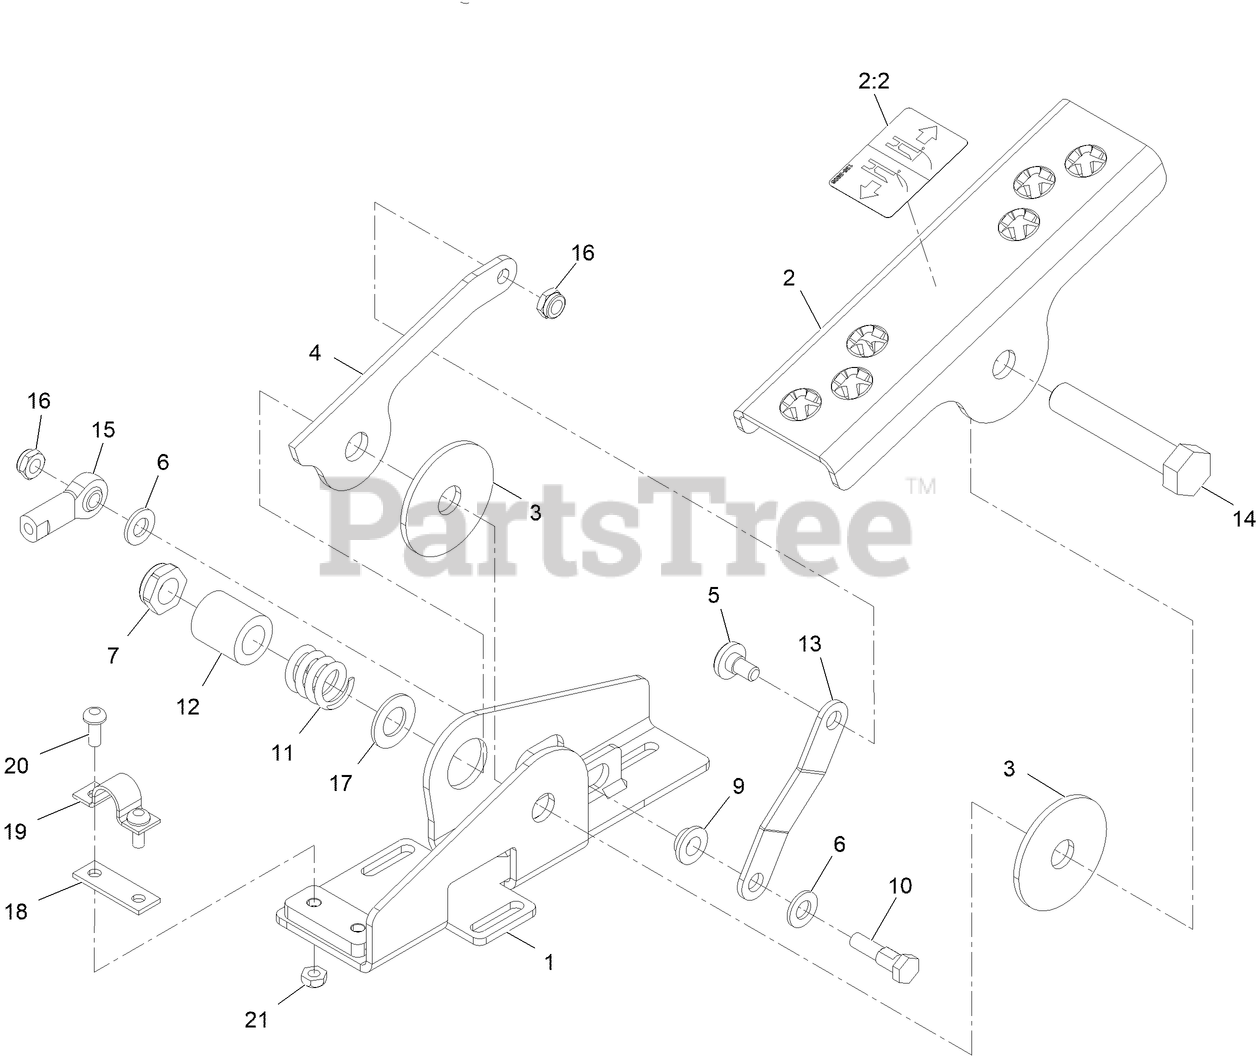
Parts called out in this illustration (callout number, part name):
1	WELD, PEDAL MOUNT
2	ASM-PEDAL LINK CHANNEL W/DECAL
2:2	DECAL-OCD OPERATION
3	DISC-FRICTION
4	Arm- Foot Pedal
5	SCREW-SHOULDER
6	WASHER-FLAT
7	NUT-HEX
9	Bushing, Flange
10	BOLT-PIVOT, ECCENTRIC
11	SPRING-COMPRESSION
12	Spacer-Pivot
13	LINK, FOOT PEDAL
14	SCREW-HH
15	ROD END-BALL JOINT
16	NUT-LOCK, NI
17	SPACER
18	SHIM,CONTROL CABLE
20	SCREW-PPH
21	NUT-LOCK, NI
